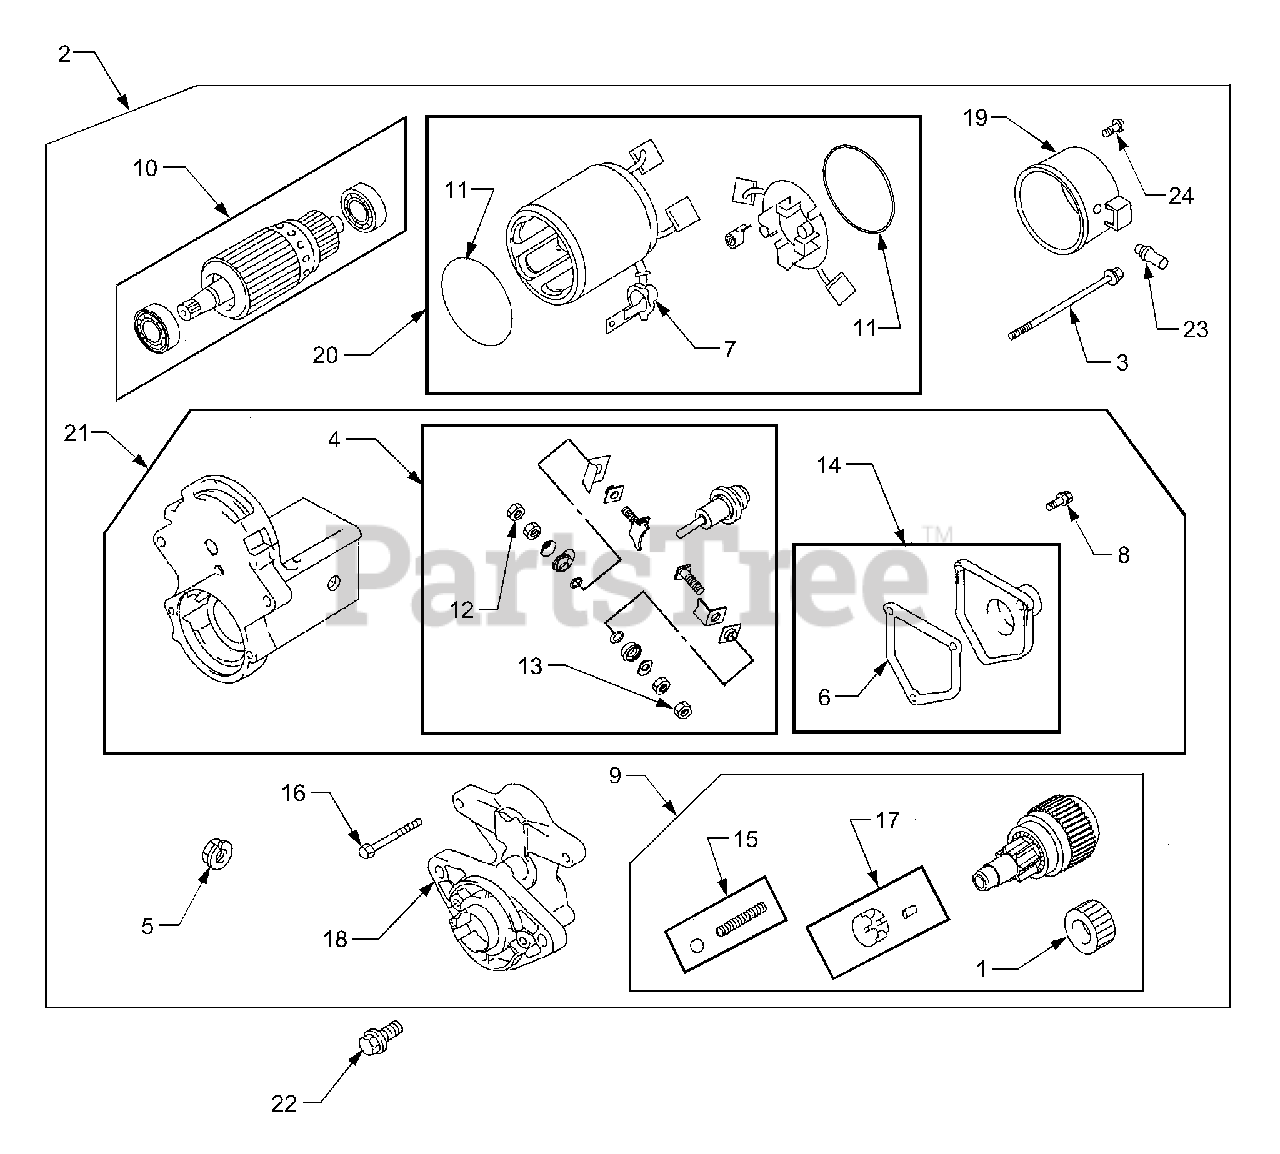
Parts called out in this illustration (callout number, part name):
1	Gear, Starter Drive
2	Motor, Starter
3	Screw, Starter Motor
4	Terminal Kit, Solenoid
5	Nut, Starter Motor Terminal
6	Gasket, Solenoid Cover
7	Boot, Terminal
8	Screw, Solenoid Cover
9	Drive, Starter
11	Seal, O-Ring
12	Nut, Solenoid Terminal
13	Nut, Solenoid Terminal
14	Cover, Solenoid
15	Spring, Detent
16	Screw, Drive Cap
17	Clutch Roller
18	Cap, Drive
20	Housing, Starter
21	Solenoid, Starter
22	Screw, Starter Motor
23	Plug, Vent
24	Screw, End Cap
